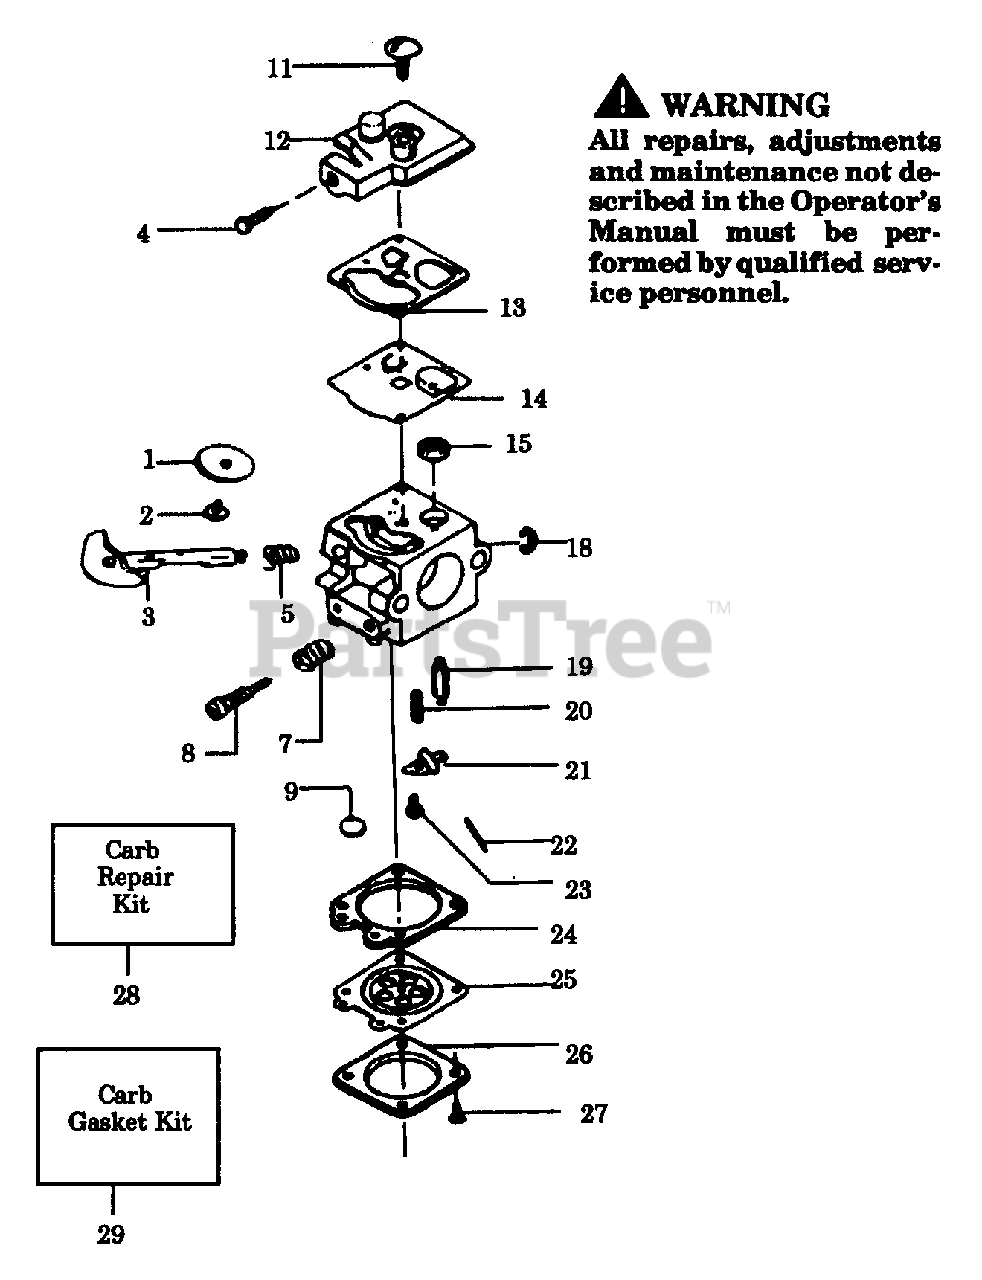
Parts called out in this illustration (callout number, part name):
1	Valve Throttle
2	Screw-Throttle Valve
3	Shaft Ass'y.-Throttle
4	Idle Speed Screw
5	Spring-Throttle Return
7	Spring-High Speed Mixture Needle
8	Needle-High Speed Mixture
9	Plug-5/16 Dia. Welch
11	Screw-Pump Cover
12	Cover-Fuel Pump
13	Gasket-Fuel Pump
14	Diaphragm-Fuel Pump
15	Screen-Fuel Inlet
18	Ring-Throttle Retainer
19	Valve-Inlet Needle
20	Spring-Metering Lever
21	Lever-Metering
22	Pin-Metering Lever
23	Screw-Metering Lever Pin
24	Gasket-Metering Diaphragm
25	Diaphragm-Metering
26	Cover-Metering Diaphragm
27	Screw Ass'y.-Metering Cover
28	Kit-Carb. Kwik Repair
29	Kit-Carb. Gasket/Diaphragm
